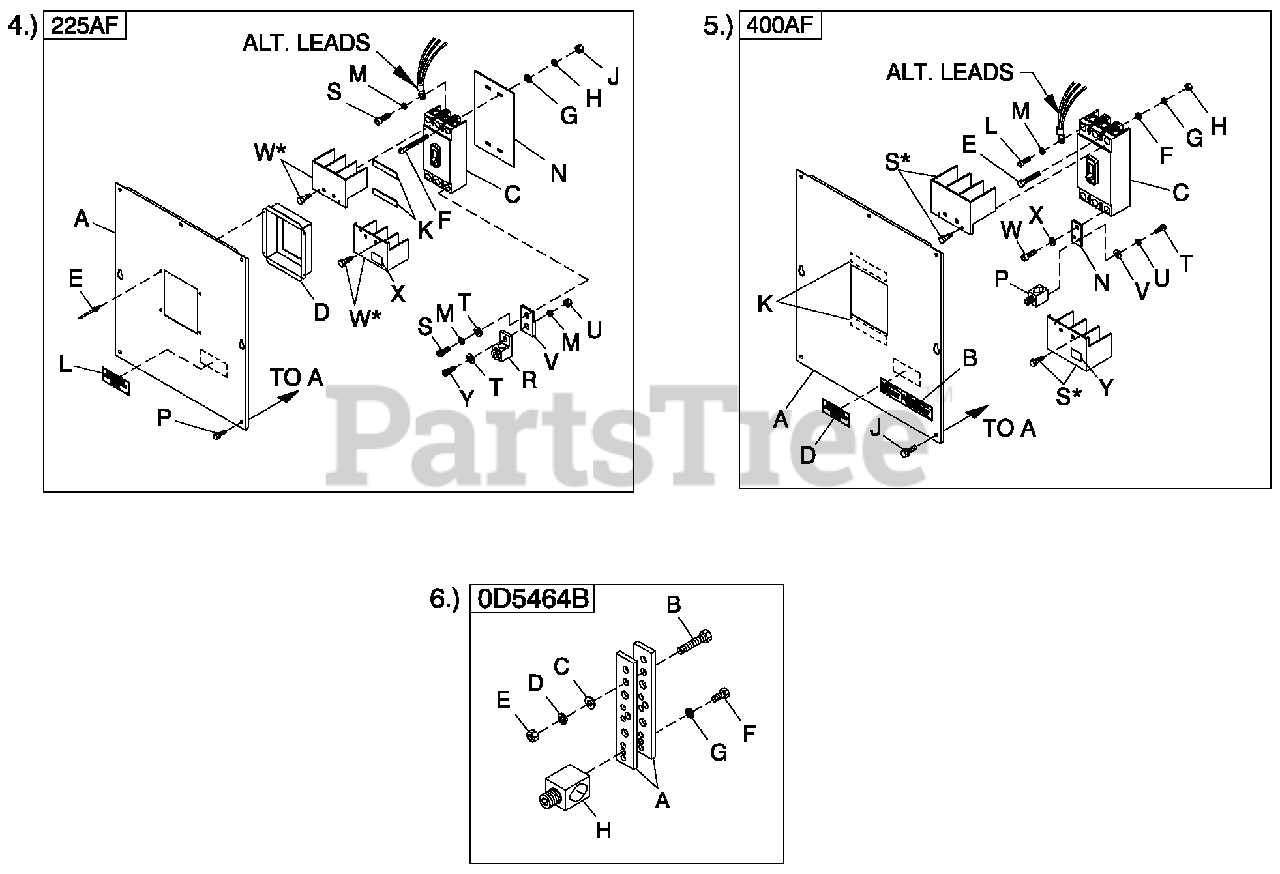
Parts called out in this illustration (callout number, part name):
A	COVER CB C3 225AF
C	CIRCUIT BREAKERS 200A FRAME
D	COVER CB DISH 225AF
E	RIVET POP .125 X .275 SS
F	SCREW RHM #8-32X3-1/4
G	WASHER FLAT #8 ZINC
H	WASHER LOCK #8-M4
J	NUT HEX #8-32 STEEL
K	TAPE ELEC 1/2 FOAM
L	DECAL CUSTOMER CONNECT INSIDE
M	WASHER LOCK M8-5/16
N	INSULATOR CB 225AF
P	SCREW THF M6-1 X 16 N WA Z/JS
R	LUG SLDLSS 300 MCM-6 AL/CU
S	SCREW SHCM8-1.25X 20 G8
T	WASHER FLAT 5/16-M8 ZINC
U	NUT HEX M8-1.25 G8 CLEAR ZINC
V	BUS BAR 200A LUG ADAPTOR
W	TERMINAL COVER CB
X	DECAL TERMINAL SHOCK HZD BI
Y	SCREW SHC M8-1.25 X 25 G12.9
A	COVER CB C3 400AF
C	CIRCUIT BREAKERS 400A FRAME
D	DECAL CUSTOMER CONNECT INSIDE
E	SCREW RHM 10-32X4
F	WASHER FLAT #10 ZINC
G	WASHER LOCK #10
H	NUT HEX #10-32 STEEL
J	SCREW THF M6-1 X 16 N WA Z/JS
L	SCREW SHC M10-1.5 X 25 G12.9
M	WASHER LOCK M10
N	BUS BAR CB ADAPTER 225-400 A
P	LUG SLDLSS 600/250-1/0 X 1/4-28
S	TERM COVER CB
T	SCREW HHC 1/4-28X1/2 G5
U	WASHER LOCK M6-1/4
V	WASHER FLAT 1/4-M6 ZINC
W	SCREW SHC M10-1.5 x 25 G12.9
X	WASHER LOCK M10
Y	DECAL TERMINAL SHOCK HZD BI
A	BUS BAR NEUTRAL BLOCK 390
B	SCREW HHC M8-1.25 X 45 G8.8 FT
C	WASHER FLAT 5/16-M8 ZINC
D	WASHER LOCK M8-5/16
E	NUT HEX M8-1.25 G8 YEL CHR
F	SCREW HHC 1/4-28 X 3/4 G5
G	WASHER LOCK M6-1/4
H	LUG SLDLSS 600/250-1/0X1/4-28
